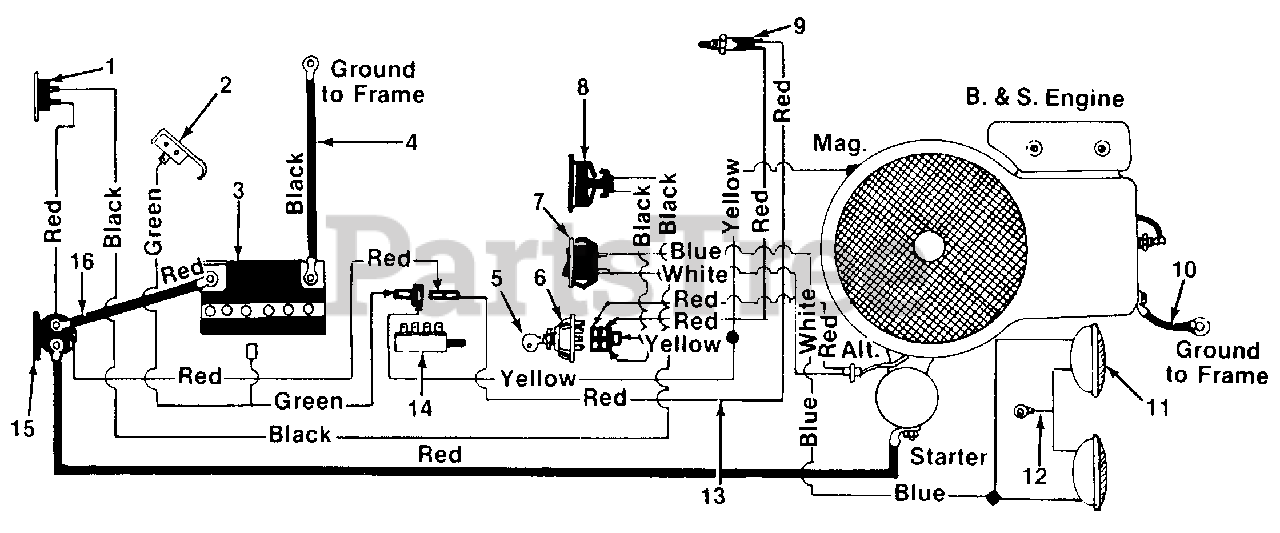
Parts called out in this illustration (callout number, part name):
1	Circuit Breaker
2	Spring Switch
3	12V-Battery
4	Grounding Wire 9.0" Lg.
5	Ignition Key
6	Ignition Switch
7	Headlight Switch
8	Ammeter
9	Safety Switch
10	Ground Wire 7.25" Lg.
11	Headlight
12	Ground Wire
13	Wire Harness
14	Safety Switch
15	Solenoid
16	Electric Wire w/ Boot
